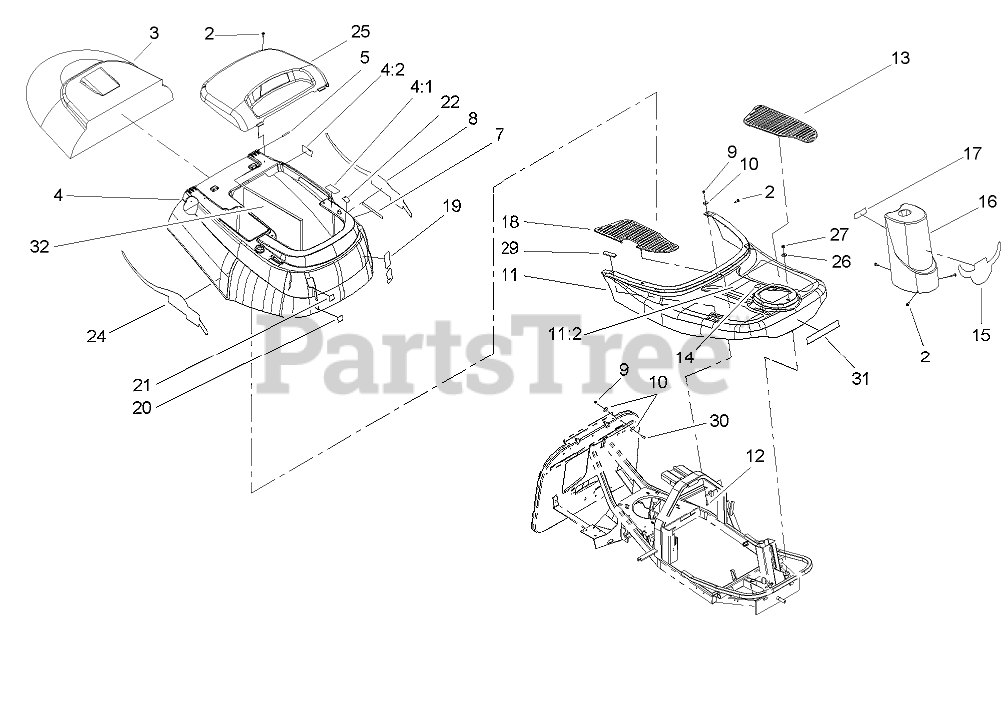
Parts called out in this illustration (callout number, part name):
2	Screw-HH, TAP
3	COVER-GRASS BAG
4	Shroud And Decal ASM
4:1	Decal-Danger
4:2	Decal-Warning, Hot
5	Pin-Dowel
7	Decal-Shift
8	DECAL-LEFT SIDE
9	NUT-LOCK
10	Washer-Flat
11	FOOT REST AND DECAL ASM
11:2	Decal-Caution
12	SCREW-HH
13	Floormat-LH
14	DECAL-CLUTCH
15	DECAL-FRONT
16	Steering-Turret
17	Decal-Run Lights
18	Floormat-RH
19	Decal-HOC
20	Decal-PTO, Disengage
21	Decal-PTO, Engage
22	Decal-Switch
24	DECAL- RIGHT SIDE
25	Cover-Engine
26	Washer-Flat
27	NUT-LOCK
30	SCREW-HH
32	INSULATION
